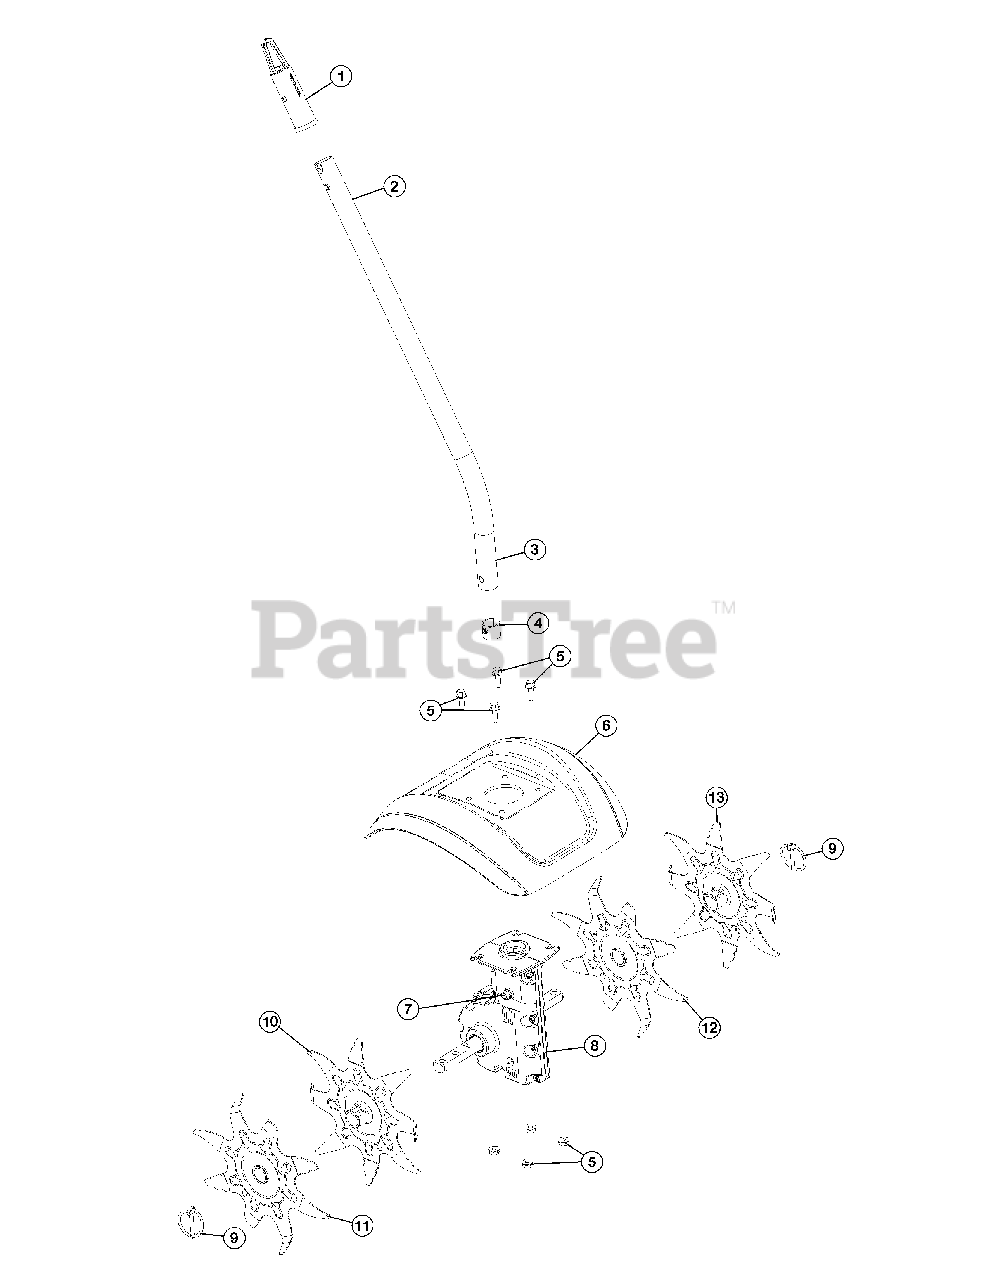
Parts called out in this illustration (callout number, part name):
1	Accessory Hanger
2	Drive Shaft Housing Assembly
3	Flexible Drive Shaft
4	Retainer Sleeve
5	Mounting Hardware Set
6	Tine Shield
7	Bolt
8	Gear Box Assembly
9	Clip Pin
10	Right Inner Tine
11	Right Outer Tine
12	Left Inner Tine
13	Left Outer Tine
